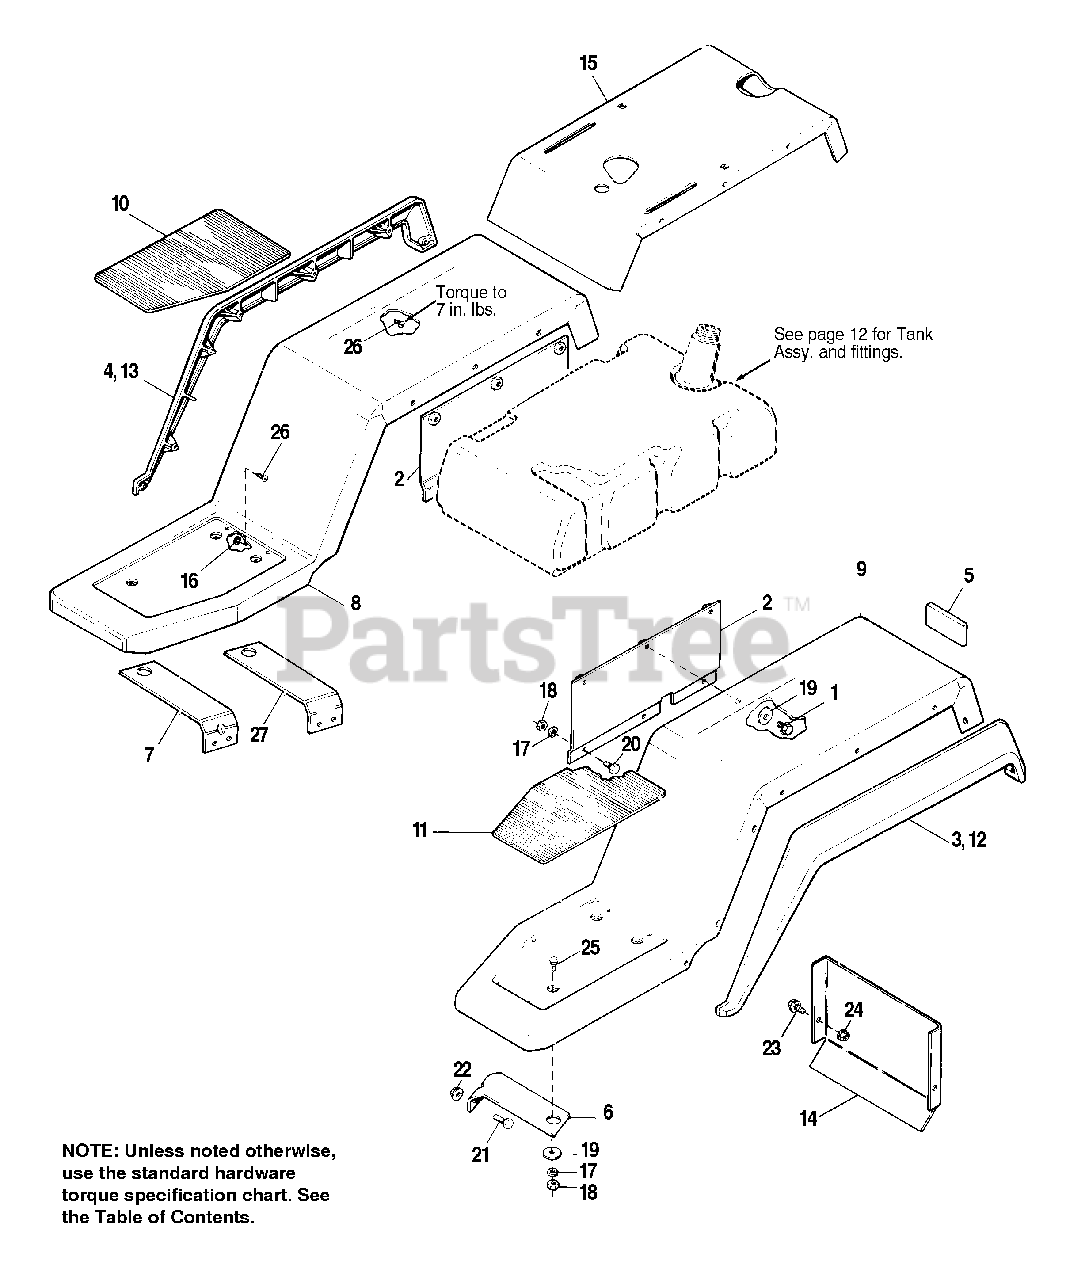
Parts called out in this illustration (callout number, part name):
1	SCREW, Taptite, 5/16-18 x 3/4
2	FENDER SUPPORT ASSY.
3	FENDER SKIRT, LH
4	FENDER SKIRT, RH
5	REFLECTOR, Rear
6	FOOTREST SUPPORT, Front, LH
7	FOOTREST SUPPORT, Front, RH
9	FENDER, LH.
10	PAD, Footrest, RH
11	PAD, Footrest, LH
12	FENDER SKIRT, LH
13	FENDER SKIRT, RH
14	COVER, Rear Frame
15	COVER, Fuel Tank
16	LOCKWASHER, 1/4
17	LOCKWASHER, 5/16
18	NUT, 5/16-18
19	WASHER, Flat, 11/32 x 1-1/2 x 7/64
20	CAPSCREW, Hex Hd., 5/16-18 x 3/4
21	CAPSCREW, Hex Hd., 3/8-16 x 7/8
22	LOCKNUT, Whiz, 3/8-16
23	SCREW, Flange, Whizlock, 5/16-18 x 1
24	NUT, Flange, Whizlock, 5/16-18
25	CARRIAGE BOLT, 5/16-18 x 3/4
26	SCREW, Plastite, 1/4-10 x 5/8
27	FOOTREST SUPPORT, Rear
